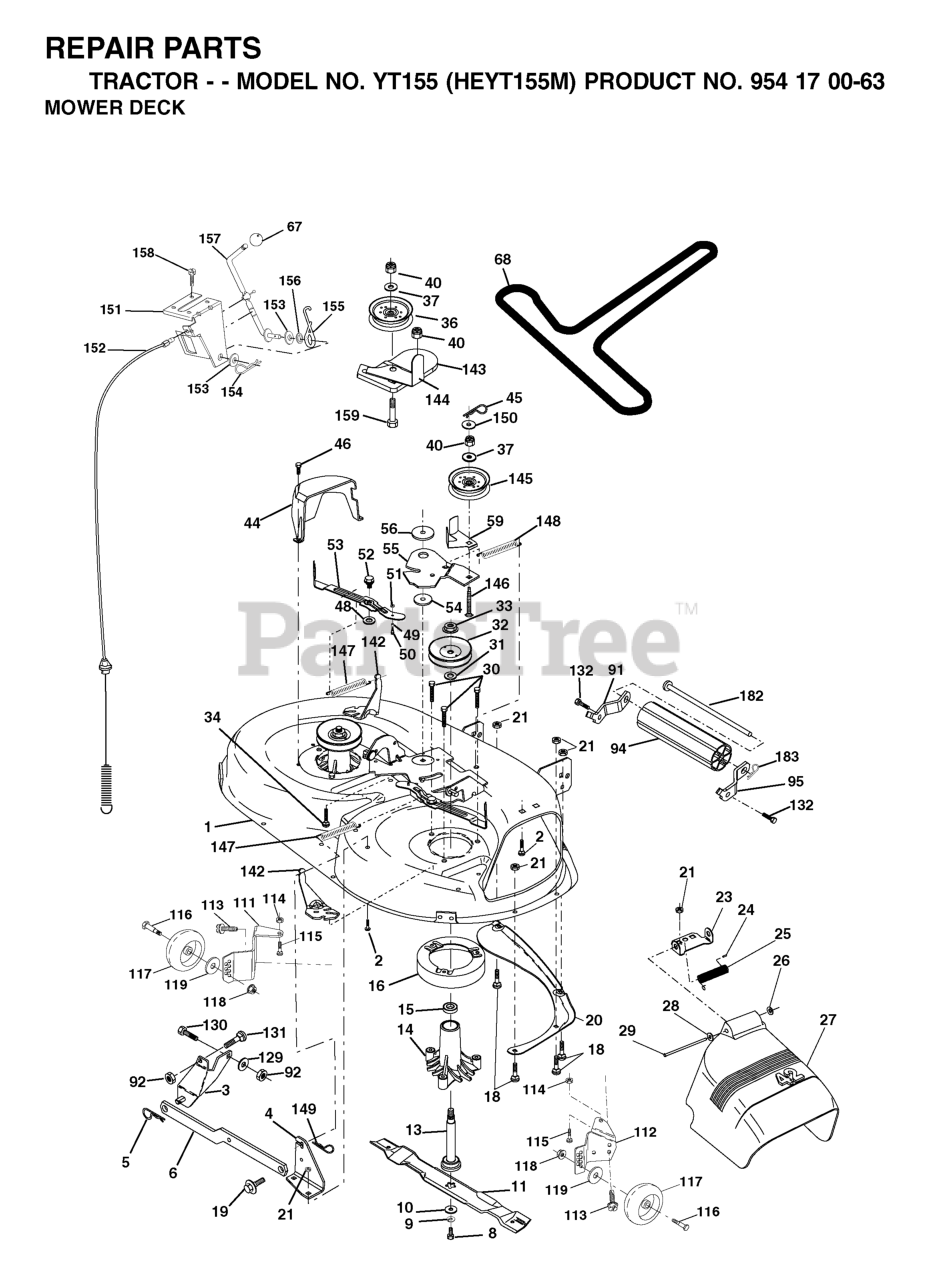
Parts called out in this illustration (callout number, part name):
1	42" DECK KIT
2	RP BOLT 5/16-18 X3/4 ZN/YEL GR
3	BRKT ASM SWAY BAR
4	BRACKET SWAY BAR 42" DECK
5	RETAINER-SPRNG RB
6	BAR SWAY DECK
8	BLADE BOLT
9	LOCKWASHER
10	WASHER.BLADE
11	Blade Mower 42" High Perf.
13	SHAFT ASM VENT
14	HOUSING.MANDREL.VENTED (MACHD)
16	STRIPPER.MANDREL.ROUND.BLACK
18	BOLT
19	BOLT SHD 5/16-18
20	BAFFLE.VORTEX
21	LOCKNUT
23	BRKT, DEFL. MOWER
24	CAP-SLEEVE LT
25	SPRING TORSION
26	NUT PUSH M
27	SHIELD DEFLECTOR
28	Washer 11/32 x 5/8 x 16 Ga SD
29	ROD.HINGE
30	SCREW, WASHER HEAD
31	WASHER
32	PULLEY/MANDREL
33	NUT, FLG TOPLOCK 9/16"
36	FLAT IDLER PULLEY
37	WASHER
44	GUARD MANDREL LH BLACK
45	RETAINER M
46	SCREW.1/4-20X5/8
49	ROLLER ASM CAM FOLLOWER
52	BOLT.SHOULDER.5/16-18
53	ARM
54	HARDENED WASHER
55	ARM IDLER 42" MOWER LT/YT
56	SPACER.RETAINER.MOWER
59	GUARD, BELT
67	KNOB T (3/8 HOLE)
91	BRACKET ASM NOSEROLLER LH
92	NUT
94	NOSE ROLLER
95	BRACKET ASM NOSEROLLER RH
111	BRACKET, WHEEL
112	BRACKET, WHEEL
113	Screw Tapping 3/8-16 x .625
114	NUT
115	BOLT.CARR.5/16-18X5/8.SHORT
116	BOLT M
117	WHEEL.GAUGE.STANDARD
118	LOCKNUT
119	WASHER.5/16.FLAT.STE.STD.
129	WASHER
131	BOLT D
132	SCREW 3/8-16X3/4
142	ARM SPRING BRAKE MOWER
143	BRACKET, ARM IDLER
144	DNO KEEPER.BELT.42".CLUTCH.CBL
145	PULLEY
146	BOLT, CARRIAGE IDLER BLACK
148	IDLER RETURN SPRING
149	SPRING.RETAINER.YELLOW.ZINC
151	BRACKET.CLUTCH.CABLE
152	CABLE.CLUTCH.42"
153	WASHER FLAT 3/8"
154	SPRING RETAINER
155	SPRING RETENTION LEVER
156	SPACER.CLUTCH.CABLE
157	ROD CLUTCH CABLE 3/8"
158	SCREW
182	ROD ROLLER NOSE STANDARD
183	SPRING RETAINER
